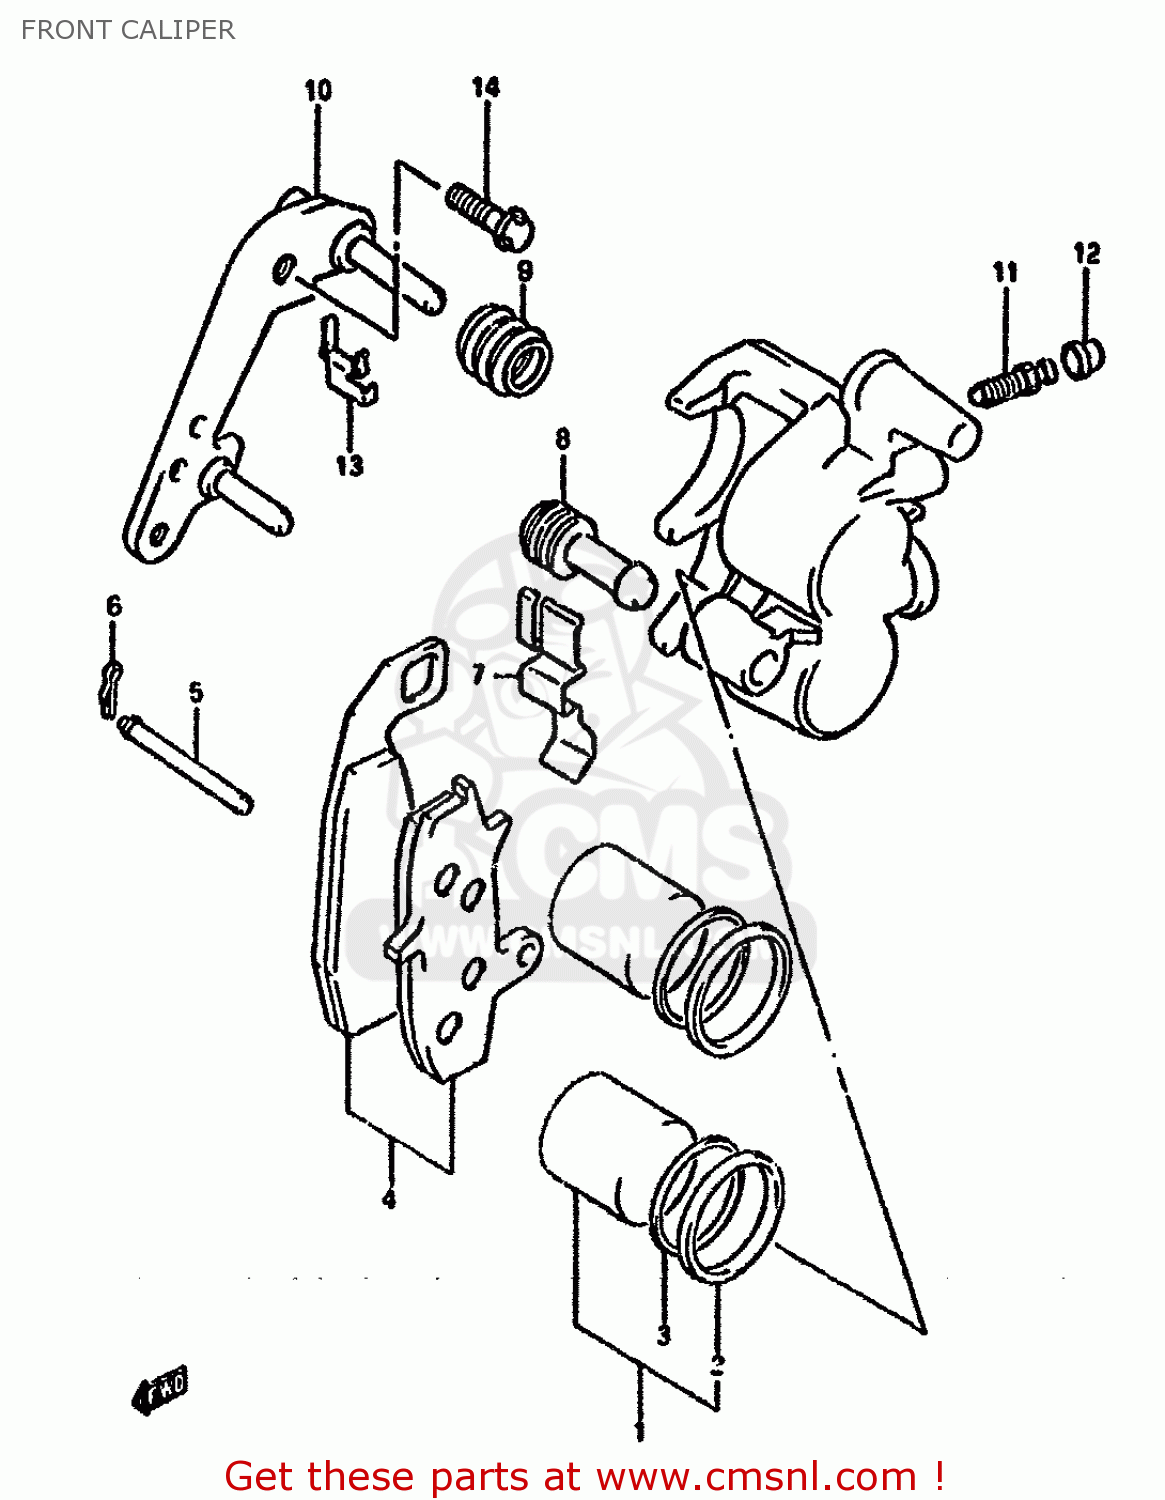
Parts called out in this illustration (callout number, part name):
1	PISTON SET
2	SEAL,PISTON
3	SEAL,WIPER
4	PAD SET (NAS)
5	PIN,PAD
6	CLIP,PAD PIN
7	SPRING,PAD
8	INSULATOR,AXLE
9	BOOT,AXLE
10	BRACKET
11	BLEEDER
12	CAP,BREATHER
13	GUIDE,PAD
14	BOLT
